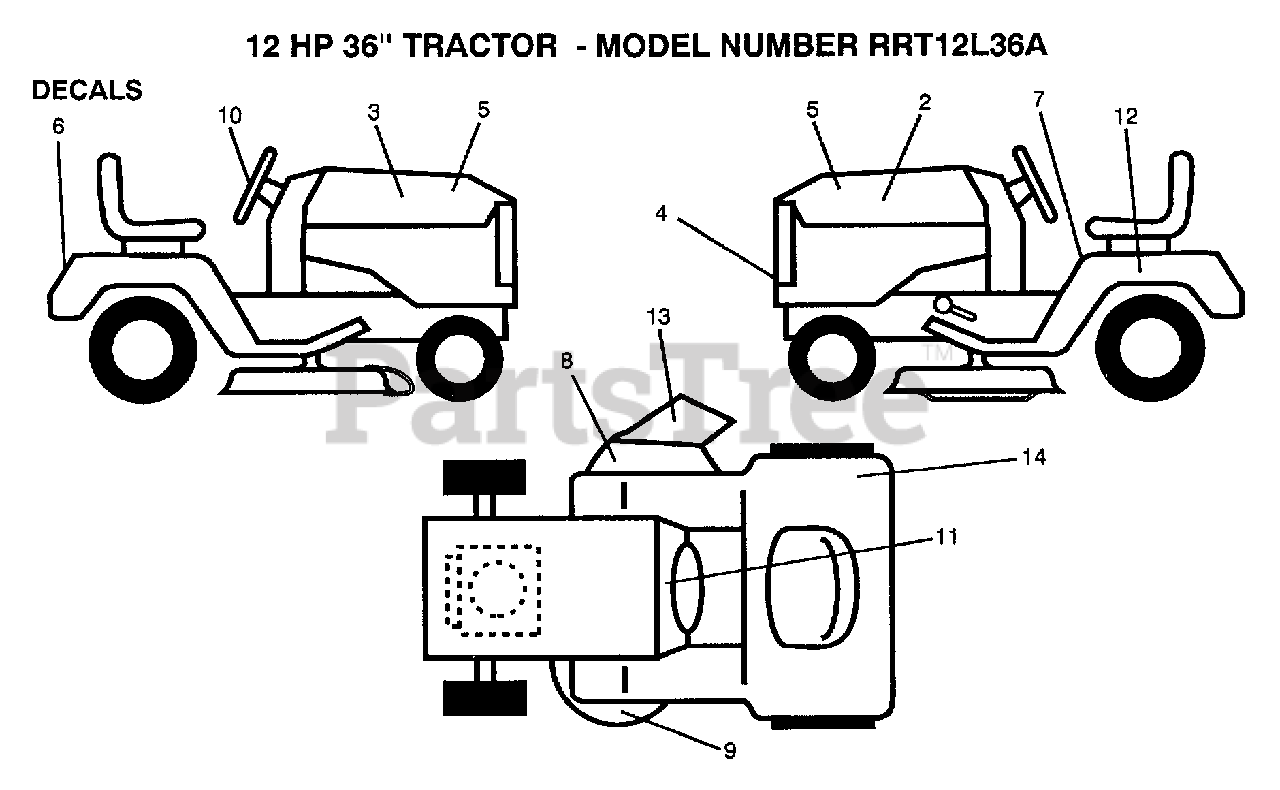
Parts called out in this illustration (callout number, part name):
2	"DECAL,STP HD LH"
3	"DECAL,STP HD RH"
4	GRILL DECAL
5	"DECAL,HOOD"
6	FENDER DECAL
7	DECAL CAUTION
8	DECAL WARNING
9	DECAL YT
10	"DECAL,STR WHL"
12	DECAL
13	DECAL WARNING
